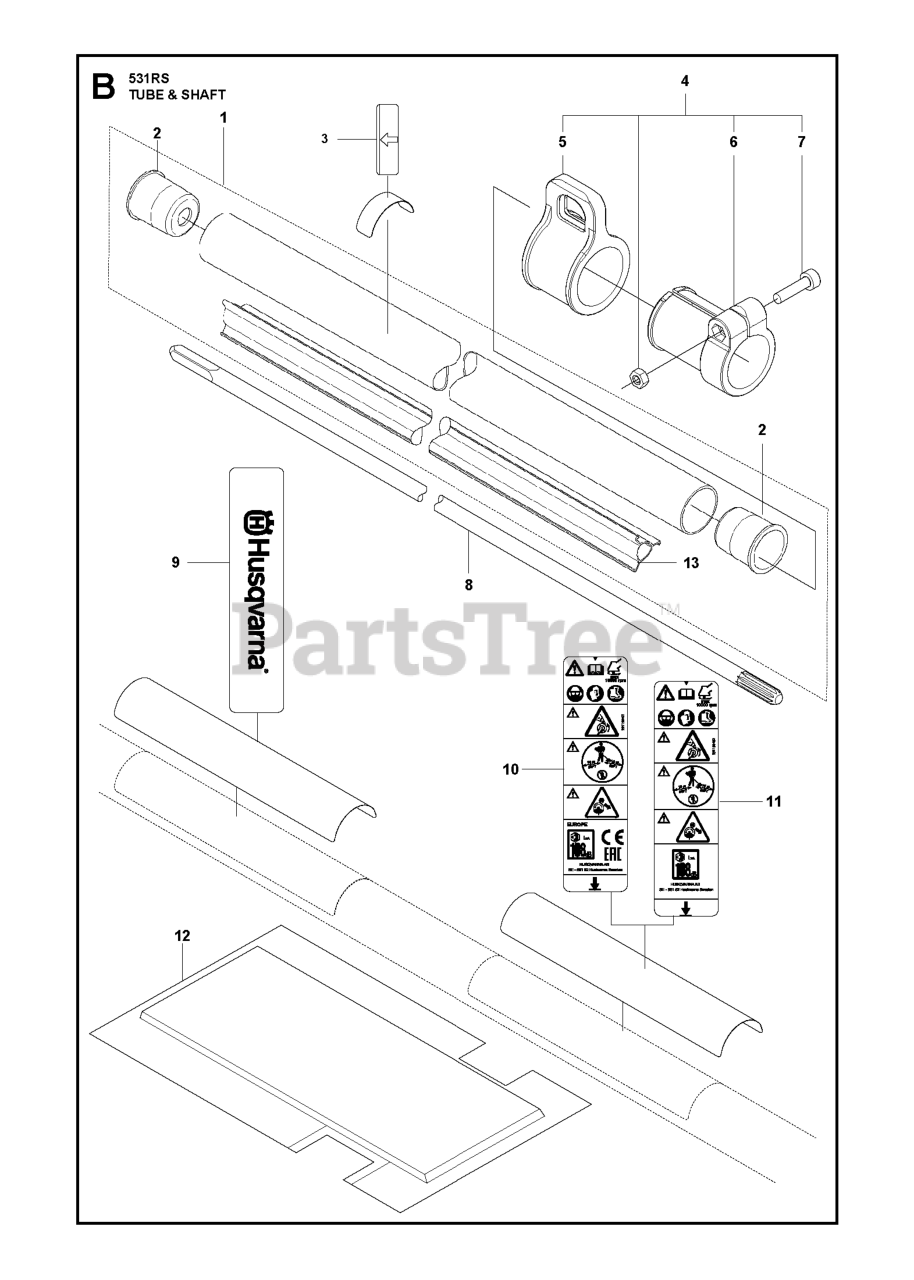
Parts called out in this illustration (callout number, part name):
3	LABEL
7	BOLT
8	DRIVE SHAFT
12	PROTECTOR (RPLS 405017110)
